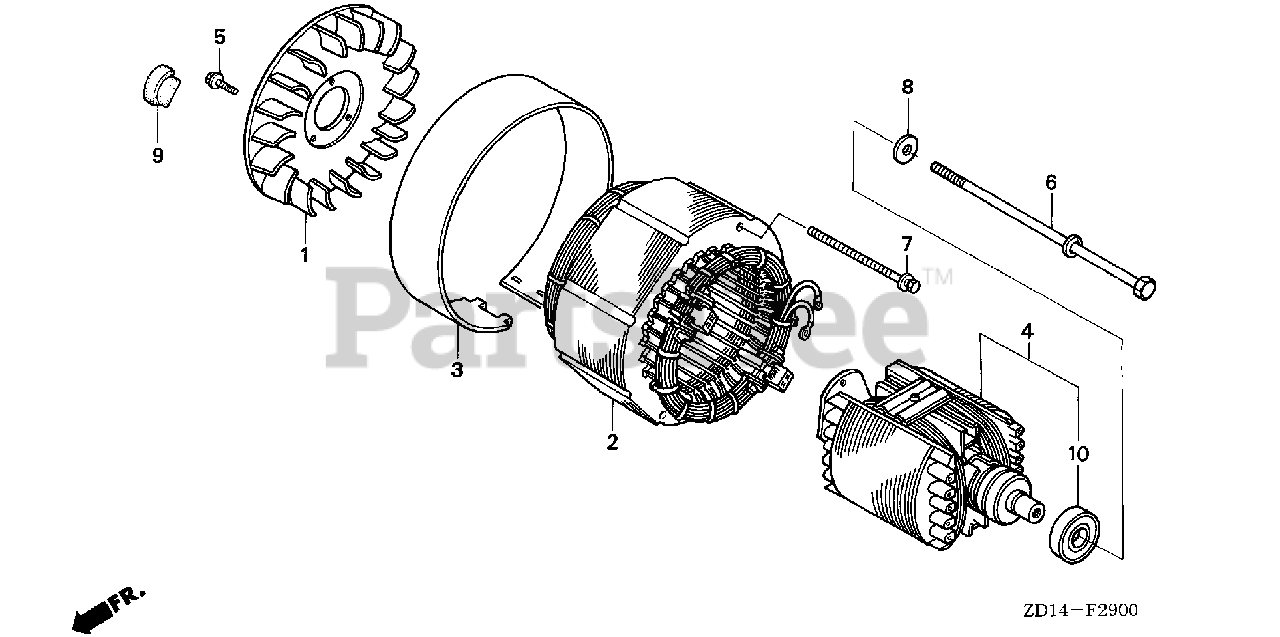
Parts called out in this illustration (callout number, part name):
1	FAN, GENERATOR COOLING
2	STATOR ASSY.
3	COVER, STATOR
4	ROTOR
5	SCREW, TAPPING (5X14)
6	BOLT, HEX. (10X265)
7	BOLT-WASHER (5X210)
8	WASHER (10.5MM)
9	GROMMET, CRANKCASE
10	BEARING ASSY. (6204)
